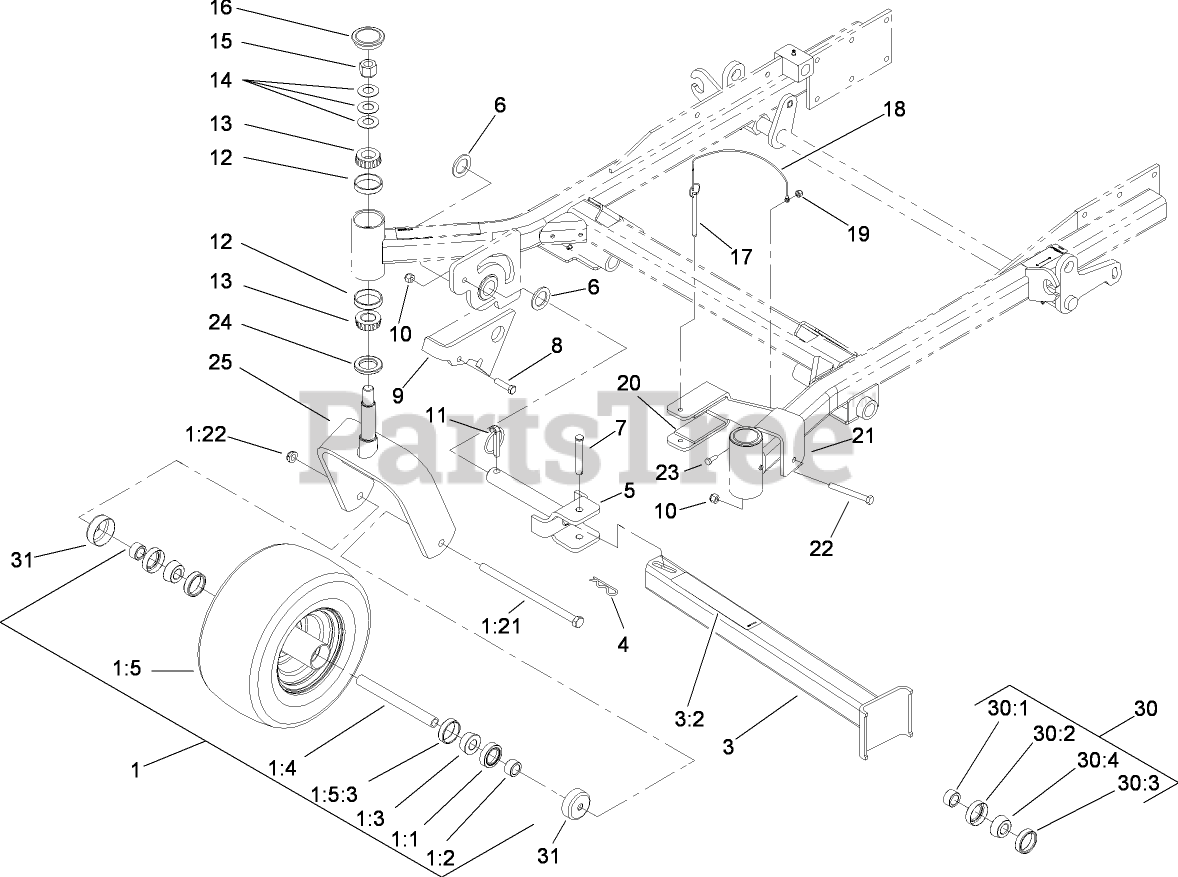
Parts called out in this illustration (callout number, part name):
1	CASTOR WHEEL ASM
1:1	SEAL-BEARING
1:2	SPACER-BEARING
1:3	BEARING-CONE, TAPER
1:4	SPACER-CASTER, FRONT
1:5	WHEEL AND TIRE ASM (SEMI-PNEUMATIC)
1:5:3	BEARING-CUP
1:21	SCREW-HH
1:22	NUT-LOCK, NI
3	Leg ASM
3:2	DECAL-Z STAND
4	PIN-HAIR
5	PIN-PIVOT
6	WASHER-THRUST
7	PIN-CLEVIS
8	SCREW-HH
9	BRACKET-LATCH
10	NUT-LOCK, NI
11	PIN-LYNCH
12	BEARING-CUP, TAPERED
13	BEARING-CONE, TAPERED
14	WASHER-BELLVILLE
15	NUT-LOCK, NI
16	CAP-GREASE
17	PIN-HITCH, COTTERLESS
18	LANYARD-NYLON
19	NUT-LOCK, NI
20	Cushion-Rubber
21	BRACKET-CRADLE
22	SCREW-HH
23	SCREW-HH
24	SEAL-GREASE
25	CASTER-FORK
30	CASTER WHEEL BEARING KIT
30:1	SPACER-BEARING
30:2	SEAL-BEARING
30:3	BEARING-CUP
30:4	BEARING-CONE, TAPER
31	GUARD-SEAL
